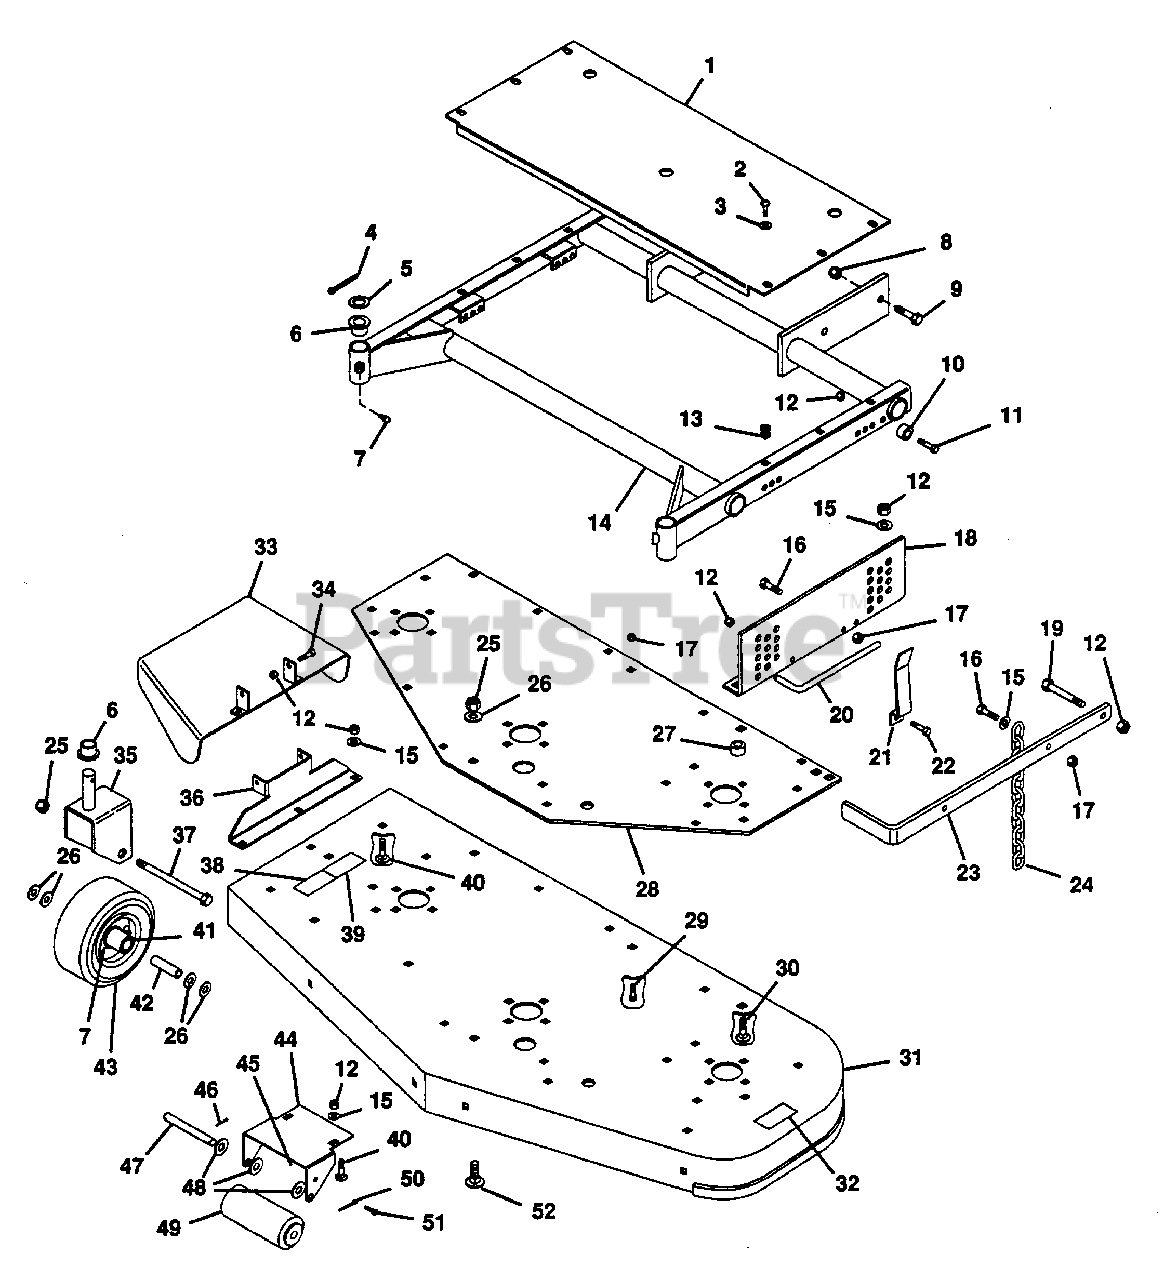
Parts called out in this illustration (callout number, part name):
1	Guard, Belt Pro-60
2	Screw, 1/4-20x.50 Self Tapping
3	Washer, Flat .281x.625x.065
4	Pin, Cotter .187x1.62
5	Race, Bearing Thrust
6	Bush., Flg. 1.03x1.75x.750 Ny.
7	Fitting, Lube 1/4-28
8	Nut, Lock 5/8-11
9	Bolt, Hex 5/8-11x1.50
10	Bush., St. .391x.621x.676 Stl.
11	Bolt, Hex 3/8-16x1.50
12	Nut, Lock 3/8-16
13	Grommet, Plastic
14	Weldment, Mower Frame
15	Washer, Flat .406x.812x.065
16	Bolt, Hex 5/16-18x1.00
17	Nut, Lock 5/16-18
18	Bracket, Mower Support L.H.
18	Bracket, Mower Support R.H.
19	Bolt, Hex 3/8-16x2.00 Full Thread
20	Pin, Mower Locking
21	Spring, Pin
22	Bolt, Hex 3/8-16x.75
23	Bar, Lift
24	Chain, Height Adjustment
25	Nut, Lock 1/2-13
26	Washer, Flat .531x1.25 x.100
27	Bush., St. .406x.750x.188 Stl.
28	Plate, 60" Support
29	Bolt, Hex 5/16-18x.75
30	Bolt, 3/8-16x1.25 Rd Hd Sq Nk
31	Weldment, 60" Mower
32	Decal, Danger Foot
33	Weldment, Discharge Chute
34	Bolt, Hex 3/8-16x1.00
35	Weldment, Caster Fork
36	Bracket, Discharge
37	Bolt, Hex 1/2-13x5.50
38	Decal, Warning Eye
39	Decal, Danger Hand
40	Bolt, 3/8-16x1.00 Rd Hd Sq Nk
41	Bearing, Gauge Wheel
42	Bush., St. .506x.748x3.34 Stl.
43	Wheel, Gauge
44	Bracket, Roller
45	Nut, Lock 1/4-20
46	Pin, Cotter .25x1.0
47	Shaft, Center Roller
48	Washer, Flat .656x1.312x.095
49	Roller, Gauge
50	Pin, Cotter .25x2.0
51	Bolt, Hex 1/4-20x.75
52	Bolt, 1/2-13x1.00 Rd Hd Sq Nk
